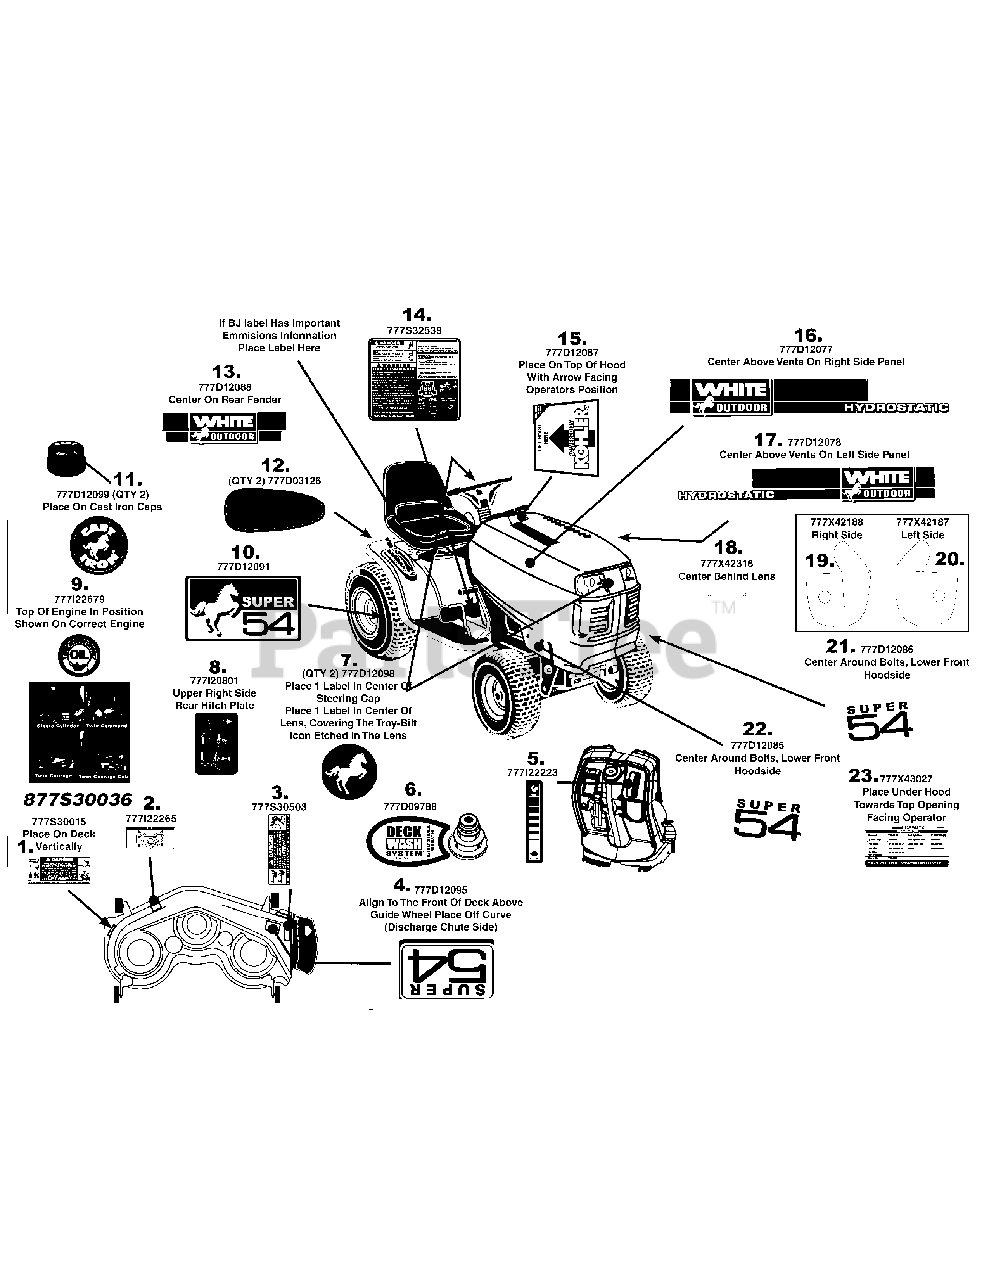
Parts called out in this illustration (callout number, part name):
1	LABEL.RIDER DNGR.STRAIGT
2	LABEL-BELT ROUTE
3	LABEL-DANGER CHUTE
4	LABEL-RIDER TOP DECK 54" CUT
5	LABEL-DASH RH
6	LABEL:RIDER:WHITE
7	LABEL-RIDER STEERING CAP WHITE
8	LABEL-HITCHPLATE
9	LABEL-CHECK ENG OIL
10	LABEL:RIDER :SD FNDR
11	LABEL-RIDER CAST IRON CAP WHITE
12	LABEL-REFLECTOR FNDR
13	LABEL-RIDER REAR FENDER WHITE
14	LABEL:RIDER:SAFETY HYDRO
15	LABEL-RIDER HOOD T KOHLER
16	LABEL-RIDER T STYLE WHITE HYDRO RH
17	LABEL-RIDER T STYLE WHITE HYDRO LH
18	LABEL-RIDER TROY MID REFL
19	LABEL-RIDER T STYLE GRILL RT
20	LABEL-RIDER T STYLE GRILL LT
21	LABEL:RIDER:T STYLE LOWER GRL LT
22	LABEL:RIDER:T STYLE LOWER GRL RT
23	LABEL:RIDER:PARTS INFO:P62TK
